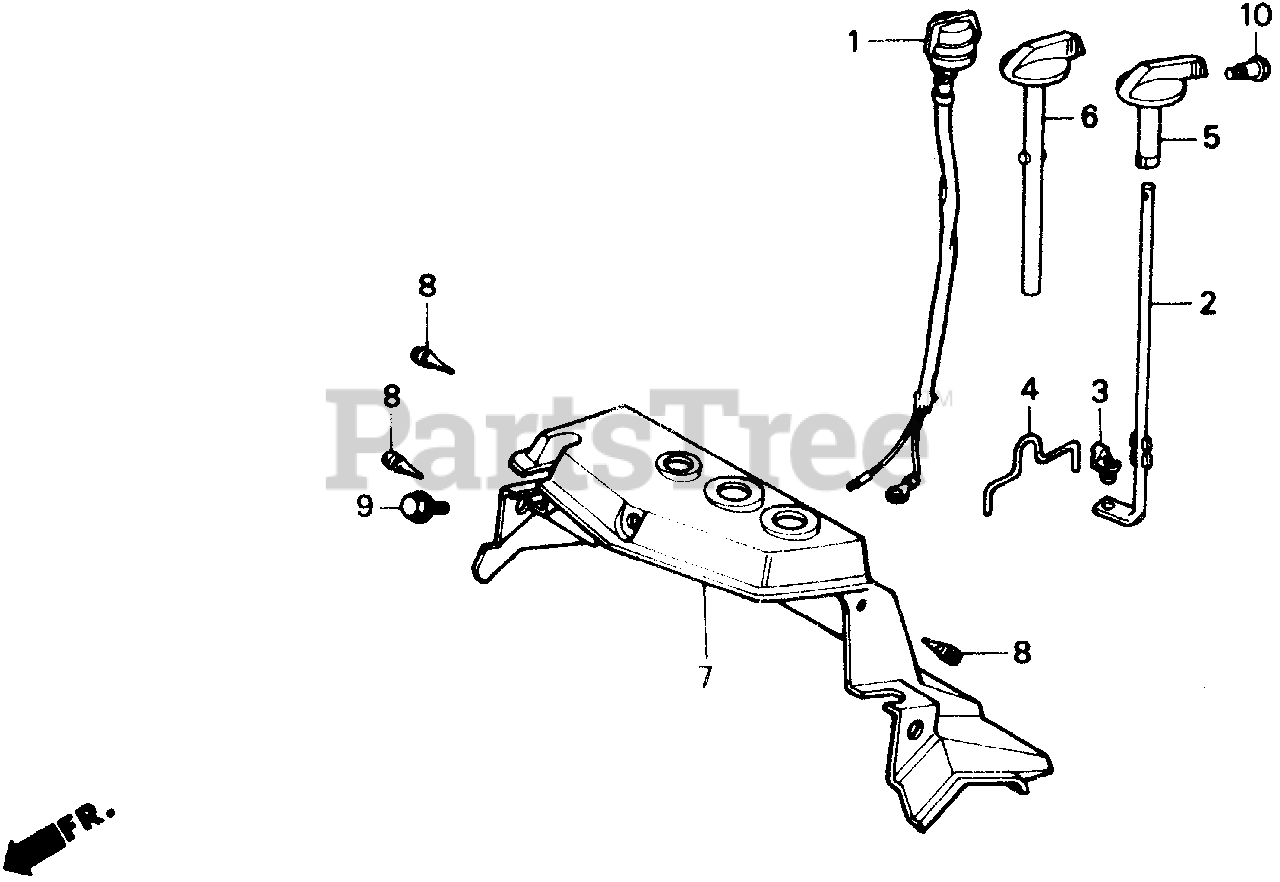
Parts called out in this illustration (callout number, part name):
1	SWITCH ASSY., ENGINE STOP
1	SWITCH ASSY., ENGINE STOP (NOT AVAILABLE)
2	SHAFT, CHOKE CONTROL (NOT AVAILABLE)
3	JOINT, ROD
4	ROD, CHOKE
5	KNOB, CHOKE CONTROL
6	KNOB, CONTROL (NOT AVAILABLE)
7	PANEL, CONTROL TOP
8	STOPPER, GLOVE BOX LID
9	BOLT, FLANGE (6MM)
10	SCREW, CHOKE KNOB (3X11)
